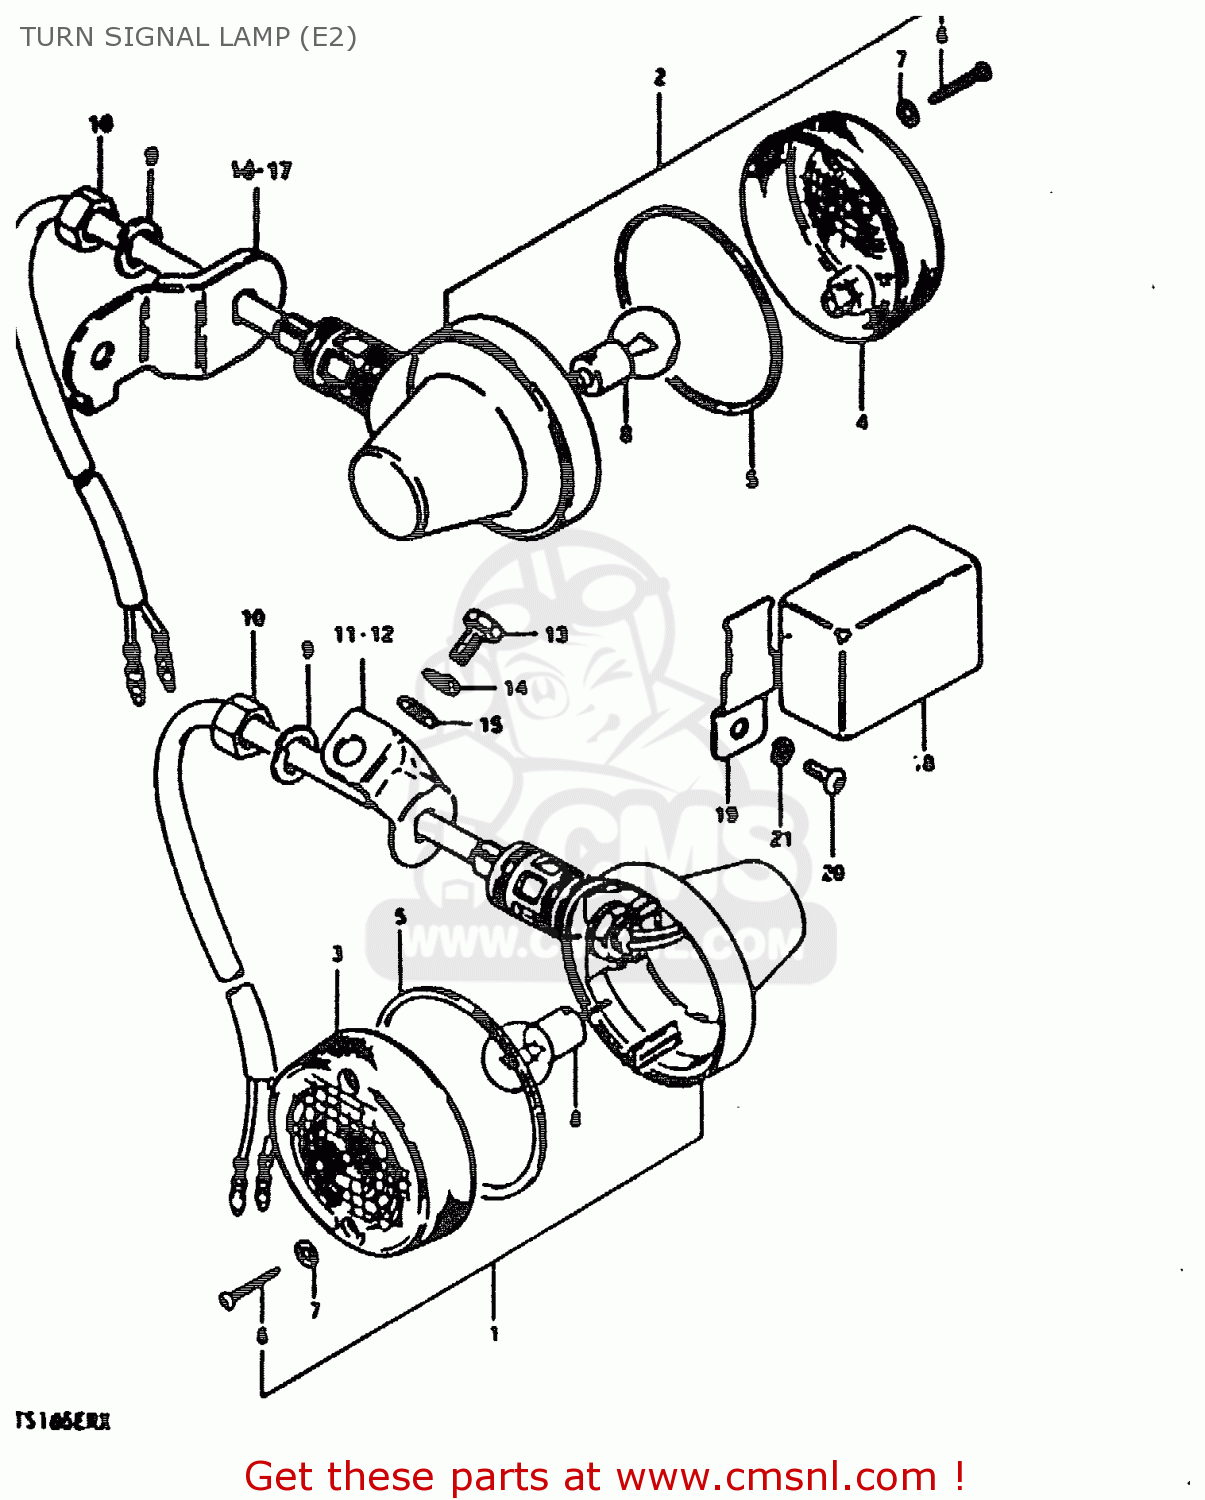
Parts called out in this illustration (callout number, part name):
1	LAMP ASSY,RR TURNSIGNAL
2	LAMP ASSY,RR TURNSIGNAL
3	LENS
4	LENS
5	GASKET (NAS)
6	SCREW TAPP.
7	GASKET (NAS)
8	BULB (6V,18W)
9	WASHER,LOCK 12
10	NUT
11	BRACKET,TURN SIGNAL LAMP
12	BRACKET,TURN SIGNAL LAMP
13	BOLT
14	LOCK WASHER
15	WASHER
16	BRACKET,REAR TURN SIGNAL
17	BRACKET,REAR TURN SIGNAL
18	RELAY,TURN SIGNAL
19	BRACKET,TURN SIGNAL RELAY
20	SCREW 6X12
21	LOCK WASHER
